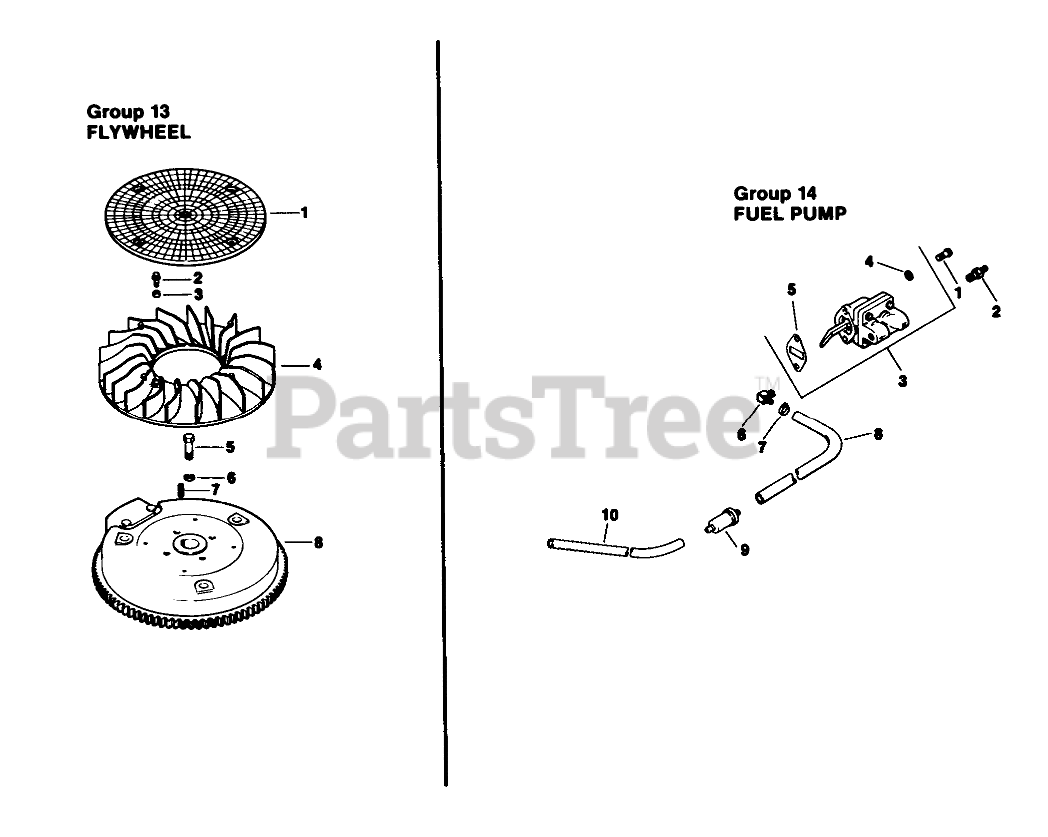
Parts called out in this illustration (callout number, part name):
1	Screen-Grass
1	Screw, F.H.
2	Screw-Hex Hd
2	Connector
3	Pump-Fuel (Incl. Ref. #4 & 5)
4	Washer
6	Connector-90deg.
7	Key
7	Clamp
8	Flywheel FUEL PUMP-GROUP 14
8	Line-Fuel
9	Filter-Fuel
20	Seal-Rear Oil
28	Screw-Hex Washer Hd.
